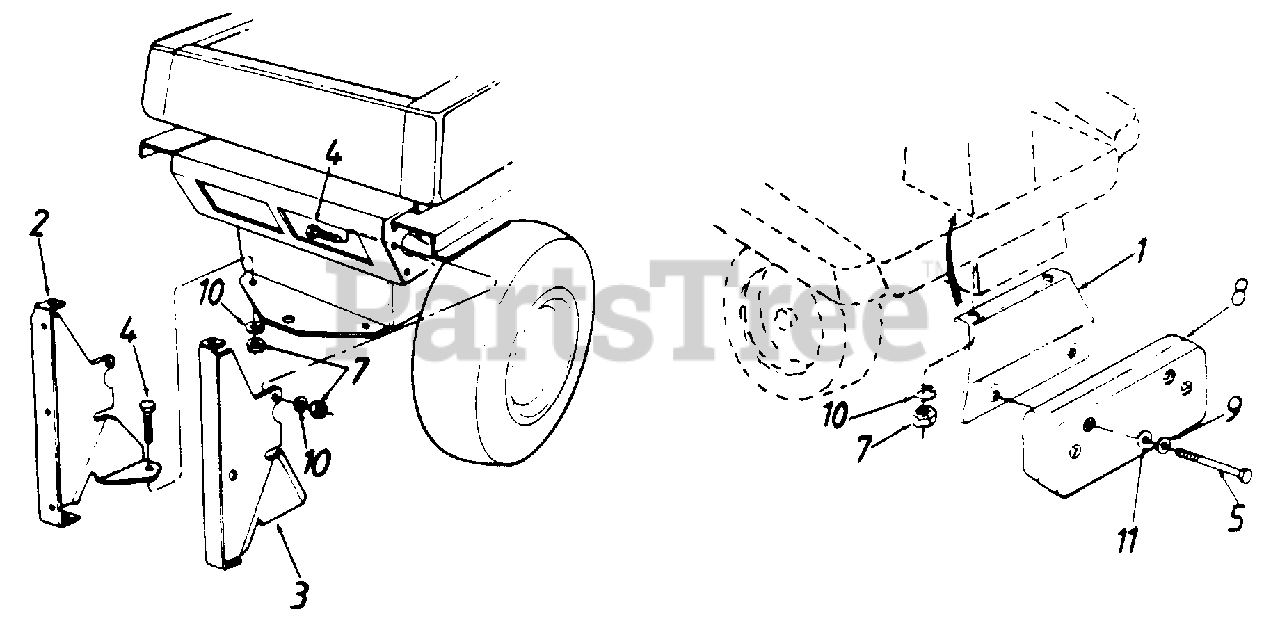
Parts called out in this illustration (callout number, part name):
1	Counterweight Support Brkt.
2	Catcher Support Brkt.- R.H.
3	Catcher Support Brkt.- L.H.
4	Hex Bolt 5/16-18 x 1.0" Lg.
5	Hex Bolt 3/8-16 x 4.5" Lg.
7	Hex Nut 5/16-18 Thd.
8	Front Counterweight
9	Bell-Wash. 3/8" I.D.
10	L-Wash. 5/16" I.D.
11	Fl-Wash. .390" I.D. x 1.12" O.D.
